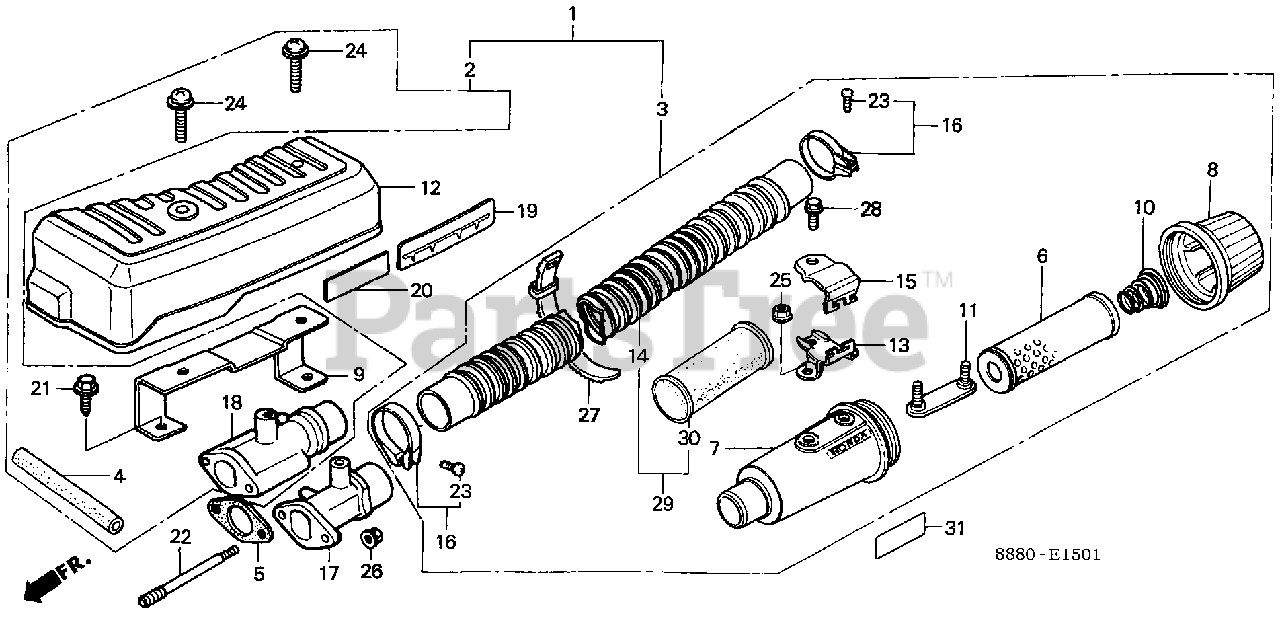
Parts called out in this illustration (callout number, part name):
1	AIR CLEANER KIT, SNORKEL JOINT
2	JOINT KIT, SNORKEL AIR CLEANER
3	AIR CLEANER KIT, SNORKEL
4	TUBE, BREATHER
6	ELEMENT, AIR CLEANER
7	HOUSING, AIR CLEANER
8	CAP, AIR CLEANER
9	STAY, CARBURETOR COVER
10	SPRING, SETTING
11	PLATE, AIR CLEANER SETTING
13	BRACKET A, AIR CLEANER
14	HOSE, AIR CLEANER
15	BRACKET B, AIR CLEANER
16	BAND, AIR CLEANER CONNECTING
18	JOINT, TUBE CONNECTING
21	BOLT, FLANGE (6X12) (CT200)
23	SCREW, PAN (4X25)
24	SCREW-WASHER (6X25)
25	NUT, FLANGE (6MM)
27	BAND B3, WIRE
28	BOLT, FLANGE (6X16)
